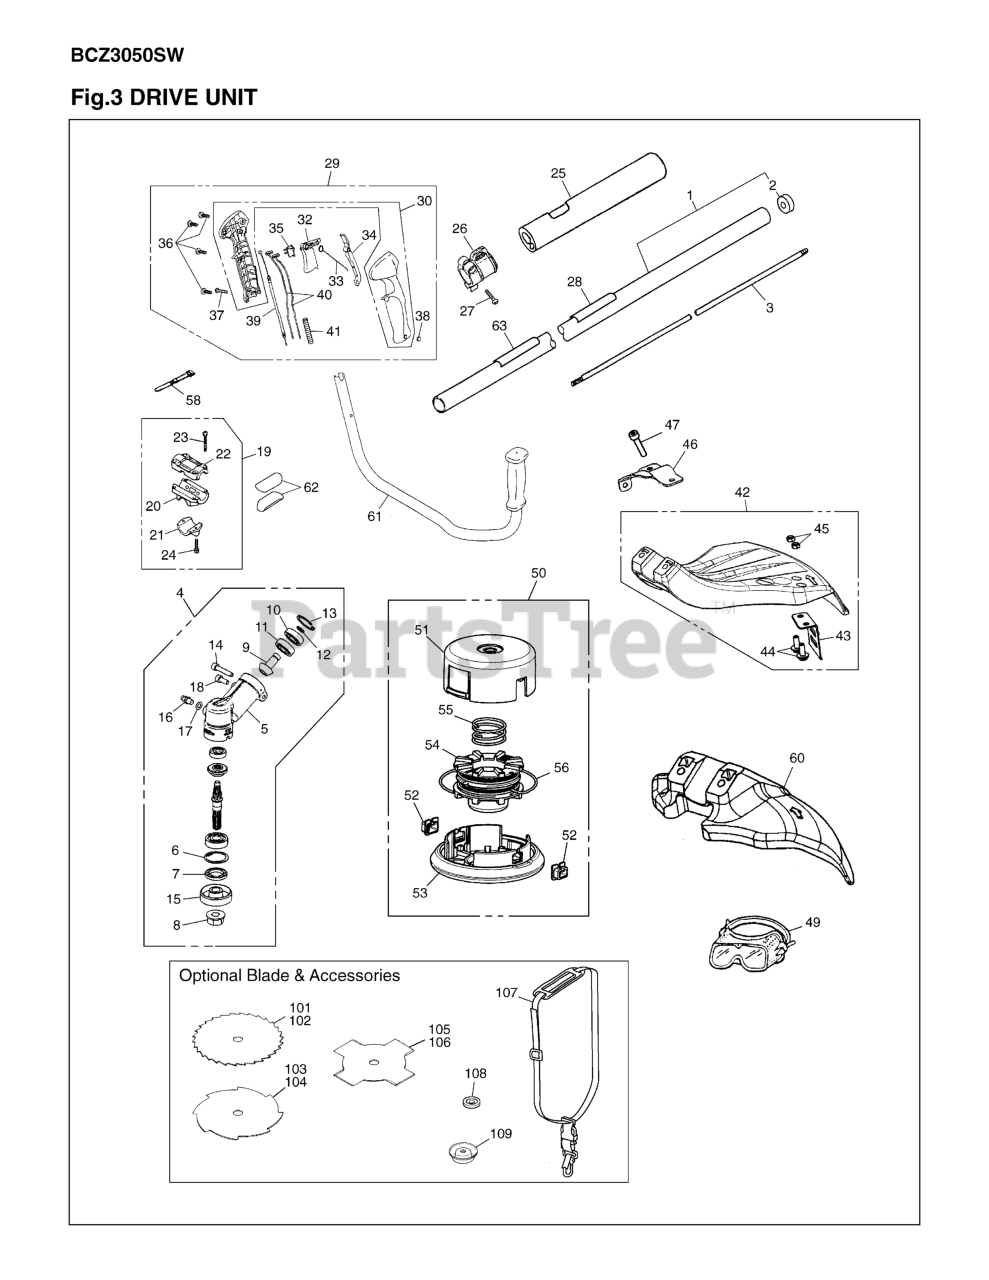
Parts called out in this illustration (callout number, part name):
1	PIPE COMP.
3	SHAFT (RPLS -122
4	GEARCASE ASSY
5	GEARCASE
6	RING,SNAP M26x1.
7	SEAL, OIL(RPLS 3
11	BEARING
12	SNAP RING
13	RING, SNAP, M24
14	BOLT, TORX
15	HOLDER (A)
16	FITTING, GREASE
17	WASHER, M6 x .8
18	BOLT, TORX
19	BRACKET ASSY
21	CAP-L
22	BRACKET-UP
23	BOLT (RPLS 28501
25	PROTECTOR
26	HANGER COMP.
28	LABEL, NAME
29	GRIP ASSY
30	HANDLE HALF SET
42	GUARD ASSY
44	SCREW
47	BOLT, TORX
49	GOGGLExxx (RPLS
50	4
52	EYELET
53	COVER (RPLS T318
54	HOLDER, CORD (RP
56	CORD
61	HANDLE COMP.
63	LABEL CAUTON FOR
101	BLADE, 9
102	BLADE, 9
103	BLADE, 8
104	BLADE, 9
105	BLADE, 8
106	BLADE, 9
107	STRAP ASSY
108	HOLDER (B)
109	COVER(10mm)(RPL2
